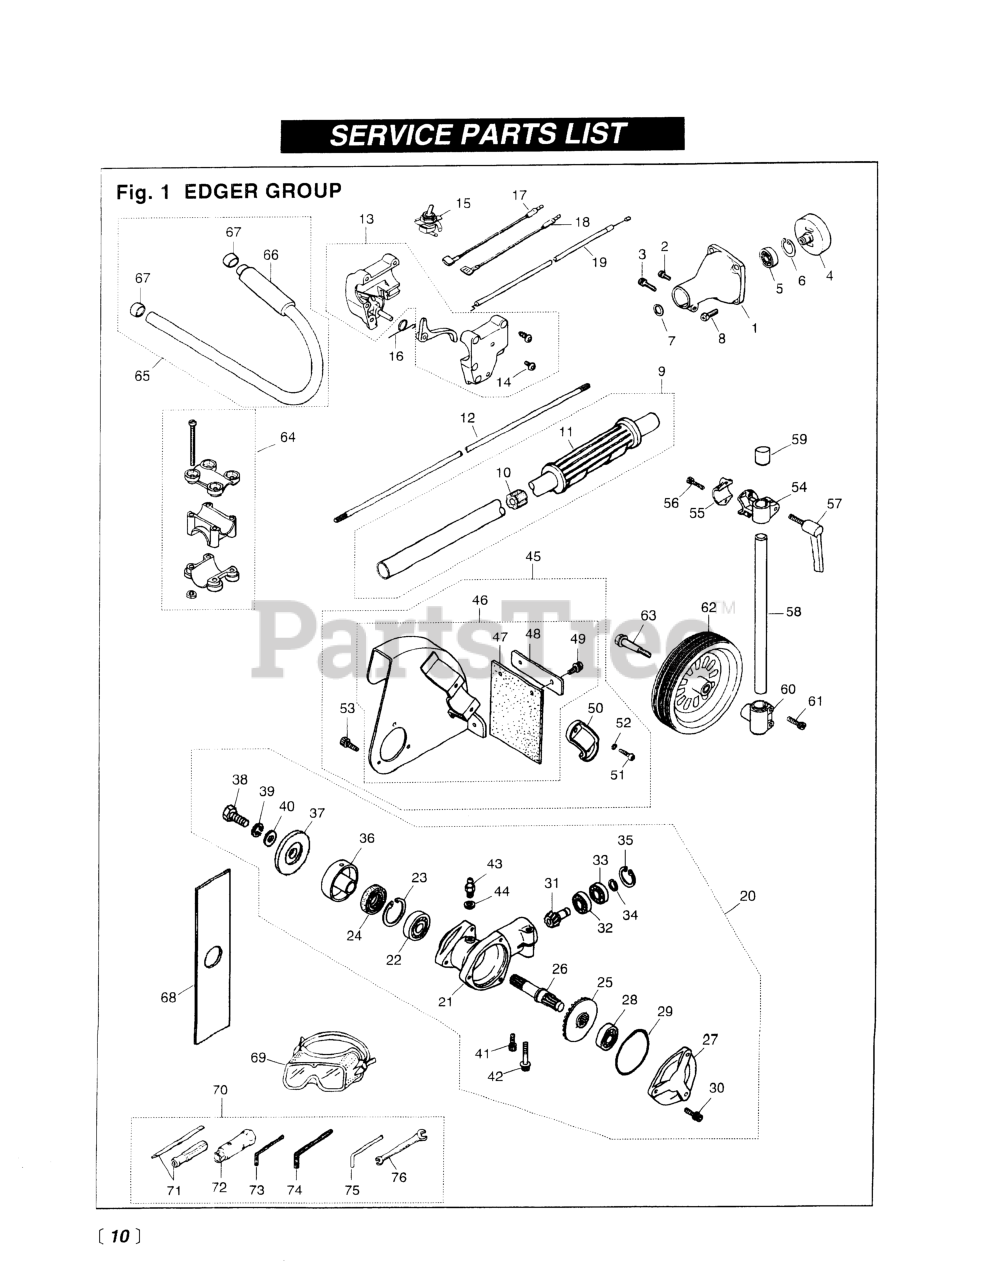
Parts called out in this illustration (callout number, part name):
2	BOLT, M5 X 10
3	BOLT, M5 X 25
4	DRUM CLUTCH (USE 6460-12112)
5	BEARING
6	RING, SNAP, M28 x 1.2
8	BOLT, M6 X 20
10	SPACER, DRIVE SHAFT
14	SET SCREW, ANTI-ROTATION
15	SPRING, THROTTLE TRIGGER
16	CORD, RED (LEAD WIRE)
17	CORD, BLACK (LEAD WIRE)
18	CABLE COMP (RPLS 6460- )
19	GEARCASE ASSEMBLY
20	GEARCASE
22	RING, SNAP, M32 x 1.2
23	SEAL, OIL
24	GEAR
25	SHAFT, GEAR
26	COVER
27	BEARING (RPLS T3403-13510)
28	O-RING
29	BOLT
30	PINION
31	BEARING (RPLS T3403-13530)
32	BEARING (RPLS T3300-13531)
33	RING, SNAP (RPLS T3300-13330)
35	HOLDER (A)
36	HOLDER (B)
37	BOLT, LH
38	WASHER (RPLS 3180-13270)
39	WASHER, M8 x 2.3 (RPLS -20823)
40	BOLT, M5 X 10
41	BOLT, M6 x 1.35
42	FITTING, GREASE
43	WASHER, M6 X .8
46	PLATE (RUBBER)
47	PLATE (REPLACES -24130)
48	BOLT, M5 X 12
49	CLAMP
50	BOLT, M6 X 18
51	WASHER, M6 X 15
52	BOLT
53	BRACKET (NLA)
55	BOLT, M5 X 22
56	LEVER
57	TUBE, EDGER
58	CAP
59	BRACKET (NO LONGER AVAILABLE)
60	BOLT, M6 X 25
61	WHEEL, EDGER
62	BOLT
63	HANDLE BRACKET ASSEMBLY
64	J-HANDLE ASSEMBLY
65	GRIP, HANDLE
66	CAP
68	GOGGLE
69	TOOL SET
70	SCREWDRIVER
72	WRENCH (TOOL)
73	WRENCH (TOOL)
74	BAR
75	SPANNER, 8 X 10 (RPLS 2540- )
